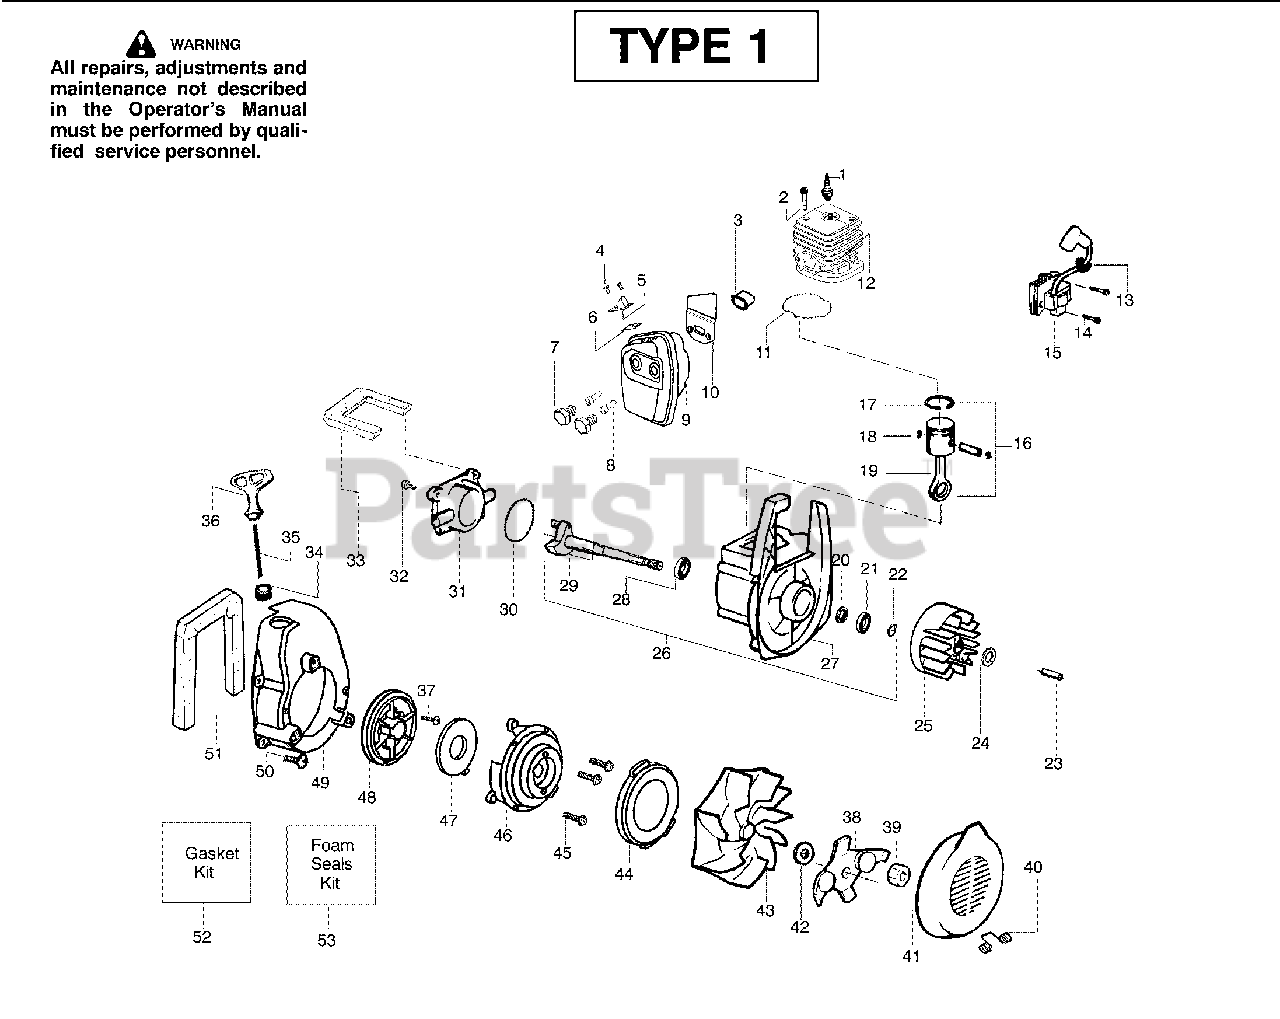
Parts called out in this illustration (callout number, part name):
1	Spark Plug (RCJ-6Y)
3	Insulator-Heat
5	Deflector-Muffler
6	Kit-Spark Screen
7	Bolt-Muffler-external
8	Screw-Muffler-Internal
9	Kit-Muffler
10	Gasket-Baffle (Kit)
11	Gasket-Cylinder (Kit)
12	Kit-Cylinder
13	Grommet-Ign. Module
14	Screw-Ignition Module
15	Ignition Module
16	Kit-Piston
17	Piston Ring
18	Retainer-Piston Pin
19	Assy-Connecting Rod
20	Seal-Crankcase
21	Bearing-Outer
22	Retainer Ring-C'chaft
23	Spacer-Flywheel
25	Assy-Flywheel
26	Assy-Crankcase/Crankshaft
27	Assy-Crankcase
28	Bearing-Inner
29	Assy-Crankshaft
30	O-ring-C/case (Kit)
31	Cover-Crankcase
32	Screw
33	Foam-219mm (Kit)
34	Eyelet-Flange
35	Kit-Rope
36	Handle-Starter
37	Screw-Rope
38	Assy-Mulch Blade
40	Spring-Return Cover
41	Inlet Door
42	Washer-Belleville
43	Assy-Impeller
44	Seal-Ring
46	Housing-Pulley
47	Spring-Starter
48	Kit-Starter Pulley
49	Fan Housing
50	Screw
51	Foam-365mm (Kit)
52	Kit-Gasket
53	Kit-Foam Seals
